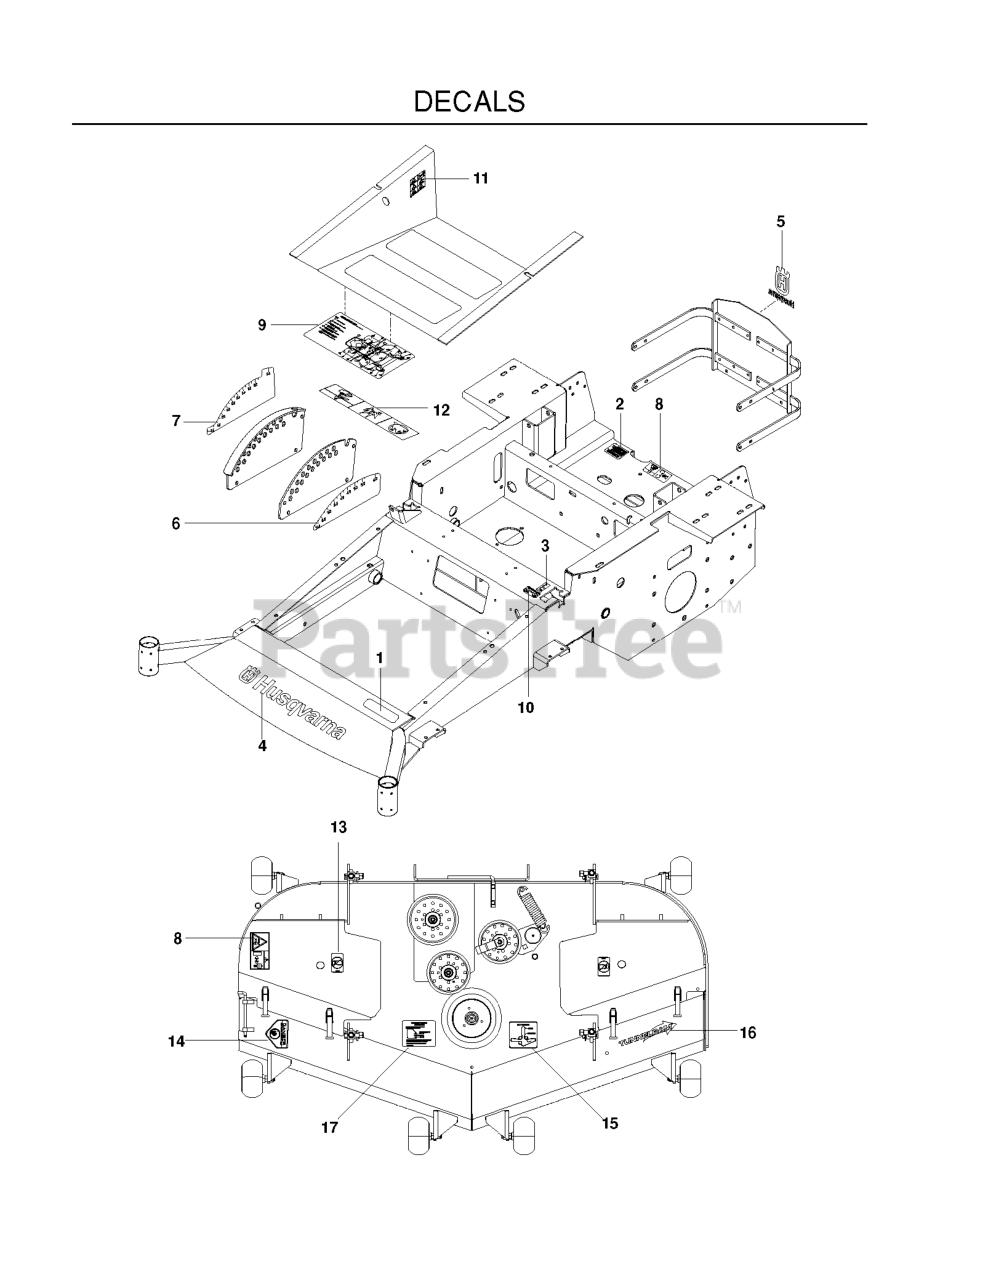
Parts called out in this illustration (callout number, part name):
1	DECAL, LZ5225
2	DECAL, PROP. 65
3	DECAL, MOTION CONTROL
4	DECAL, HUSQ 15" BLUE
5	DECAL, CROWN H 5-1/4 SILVER
6	DECAL, HEIGHT
7	DECAL, HEIGHT
8	DECAL, BELT DRIVE
9	DECAL, SERVICE
10	DECAL, F.S.T.
11	DECAL, WARNING
12	EURO DECAL-BATTERY WARNIN6
13	DECAL, NO STEP
14	DECAL, CPSC
15	DECAL, BELT ROUTING
16	DECAL, TUNNEL RAM 8"
17	DECAL, ANTI SCALP
